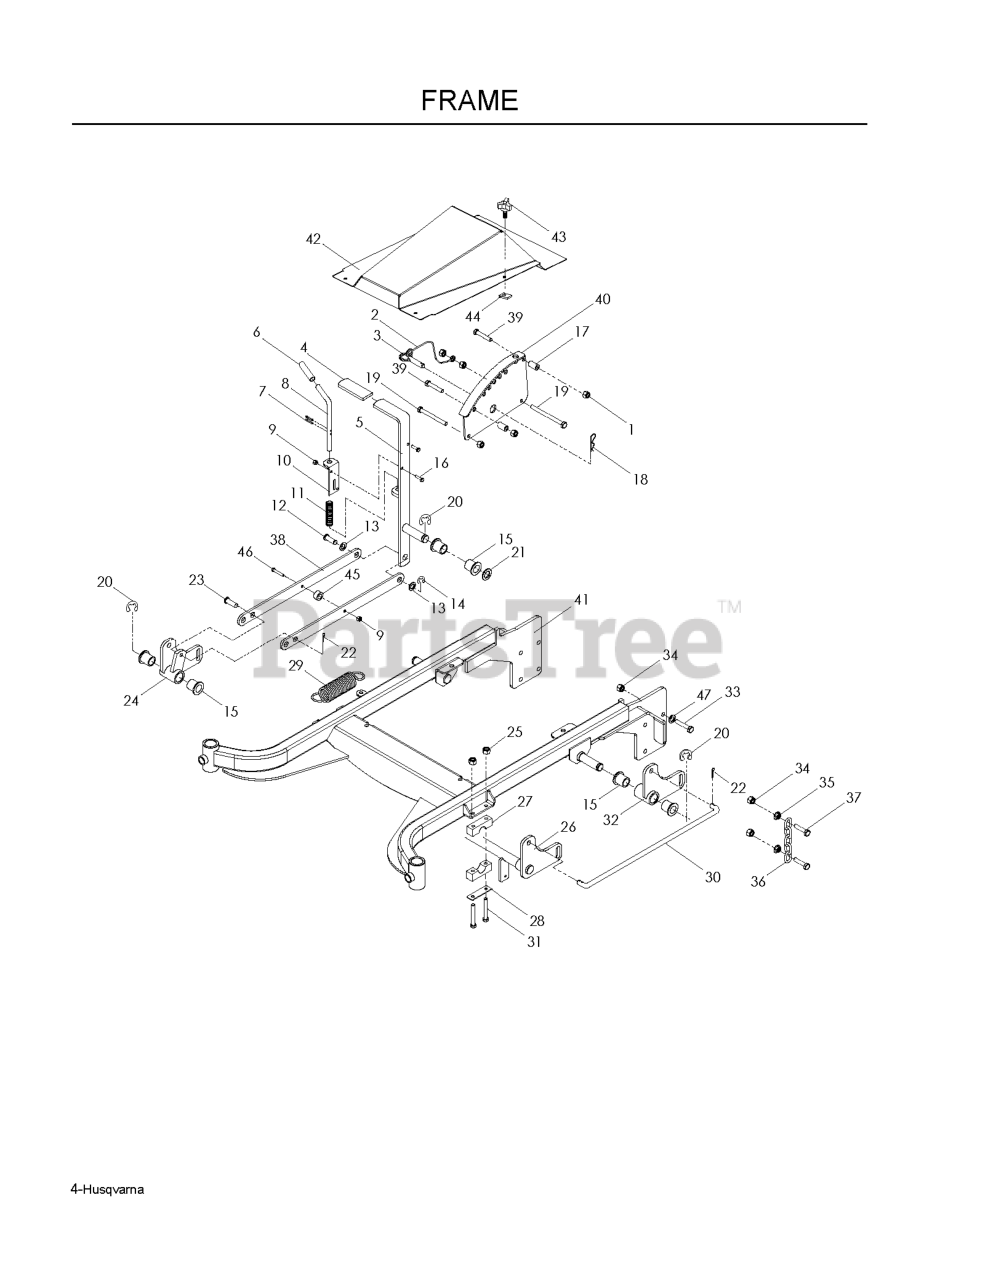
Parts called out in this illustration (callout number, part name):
1	NUT 3/8C CENTERBLOCK
5	LIFT LEVER
9	NUT 1/4C CENTER LOCK
10	PIN MT, UPPER
12	CLEVIS PIN
14	E-RING 5/8
15	BUSHING, FLANGED
16	HCS 1/4C X 3/4 HCS
17	DECK LIFT SPACER
18	HAIRPIN #4
19	HCS 3/8C X 4 1/2
20	E-RING 7/8
21	BSHG .875 X 1.375 X .074 ZD
22	COTTER PIN
23	CLEVIS PIN 3/8 X 1 1/8
24	BELLCRANK, RR-BLACK
25	NUT 5/16C CENTERLOCK
26	FRONT LIFT ARM
27	PILLOW BLOCK
28	REINFORCEMENT BAR
31	BOLT 5/16C X 2 1/2
32	BELCRANK, LR
33	HCS 7/16-14 X 1 GR 5 ZD
34	NUT 7/16C CENTERLOCK
35	NUT 7/16C WHIZ
36	LIFT CHAIN
37	HCS 7/16C X 1 1/2
38	FLAT LINKAGE
39	HCS 3/8C X 2
40	HEIGHT ADJ PLATE
41	FRONT FRAME (ORANGE)
43	KNOB W/STUD
44	U-CLIP 5/16-18 NUT RETAINER
46	BOLT HEX 1/4 X 1-1/4
47	WASHER 3/8 FLAT
